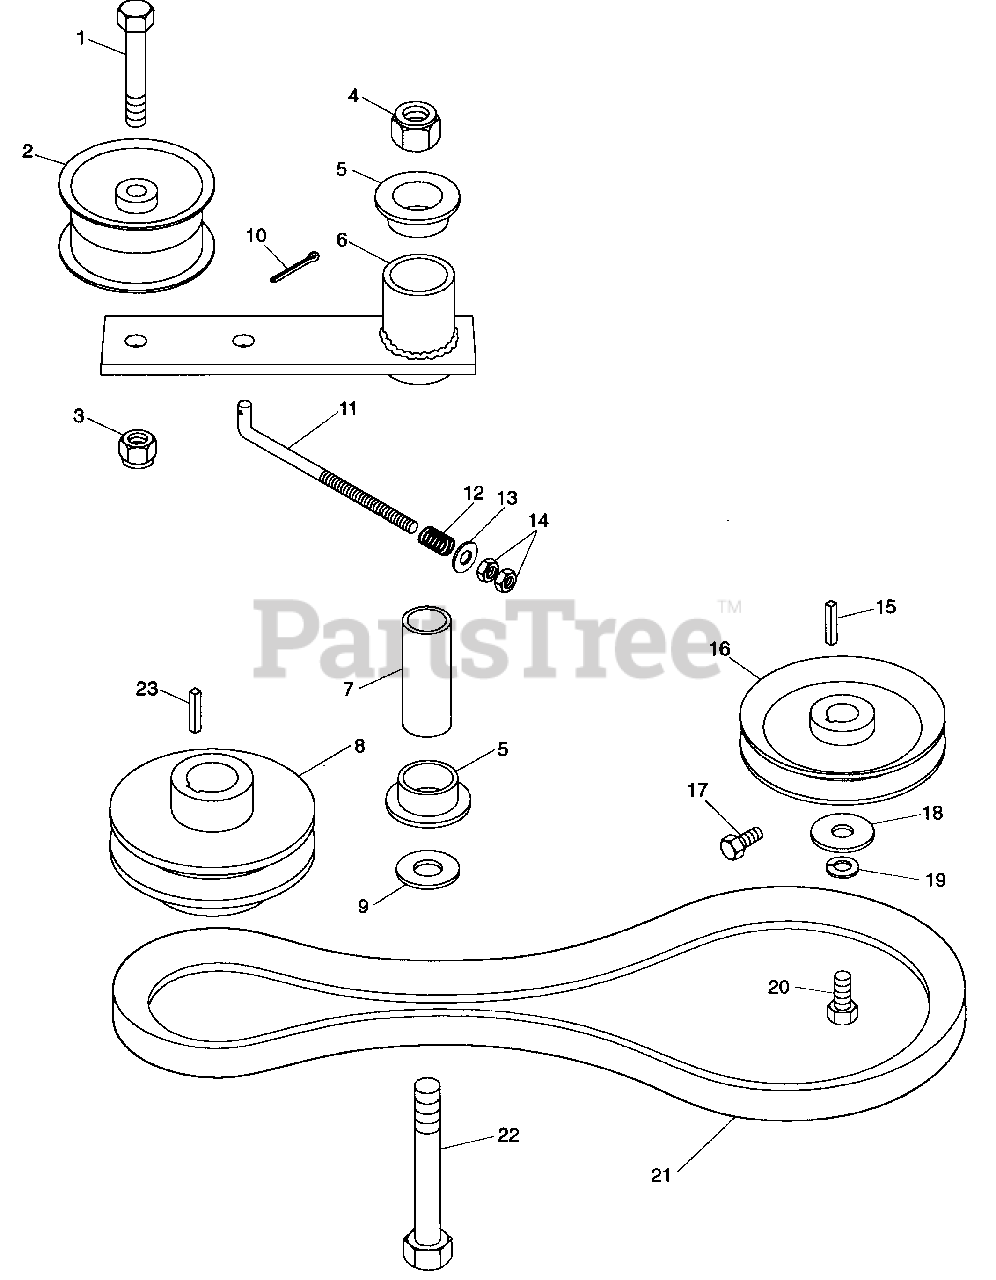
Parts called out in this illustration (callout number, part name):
1	BLT-HEX .38-16 X 1.75 PL GR 5
2	IDLER - PLY
3	NUT-LK-NYL .375-16 PL
4	NUT-LK-NYL .50-13 PL
5	BSHG-FLG .762 X 1.0 X .580 X 1.48 NY
6	WLDMT, GROUND DRIVE IDLER
7	BUSH., 5.560 X .745 X 2.04 ST
8	PLY-V 4.00 X 1.125 W/KEY
9	WSHR-FL-STL .531 X 1.062 X .095
10	PIN-COTR .09 X .75 PL
11	ROD, IDLER 11.0 LG
12	SG-COMP .188 X 1.66 X 2.0
13	WSHR-FL-STL .406 X .812 X .065 PL
14	NUT-HEX .375 X 24 ZC
15	KEY-STR 5MM X 25MM X 5MM
16	SHEAVE, HYD PUMP
17	BLT-HEX .25 X 20 X .50 PL GR 5
18	WSHR-FL-STL .281 X 1.250 X .062 PL
19	WSHR-LOCK .250 REG.
20	BLT-HEX M6 X 1.0 X 12 MM LG
21	V-BELT A-RMS 29.63 X 33/64
22	BLT-HEX .50 - 13 X 3.00
23	KEY-SQ .25 X 1.0 X .25 SAE 8630
